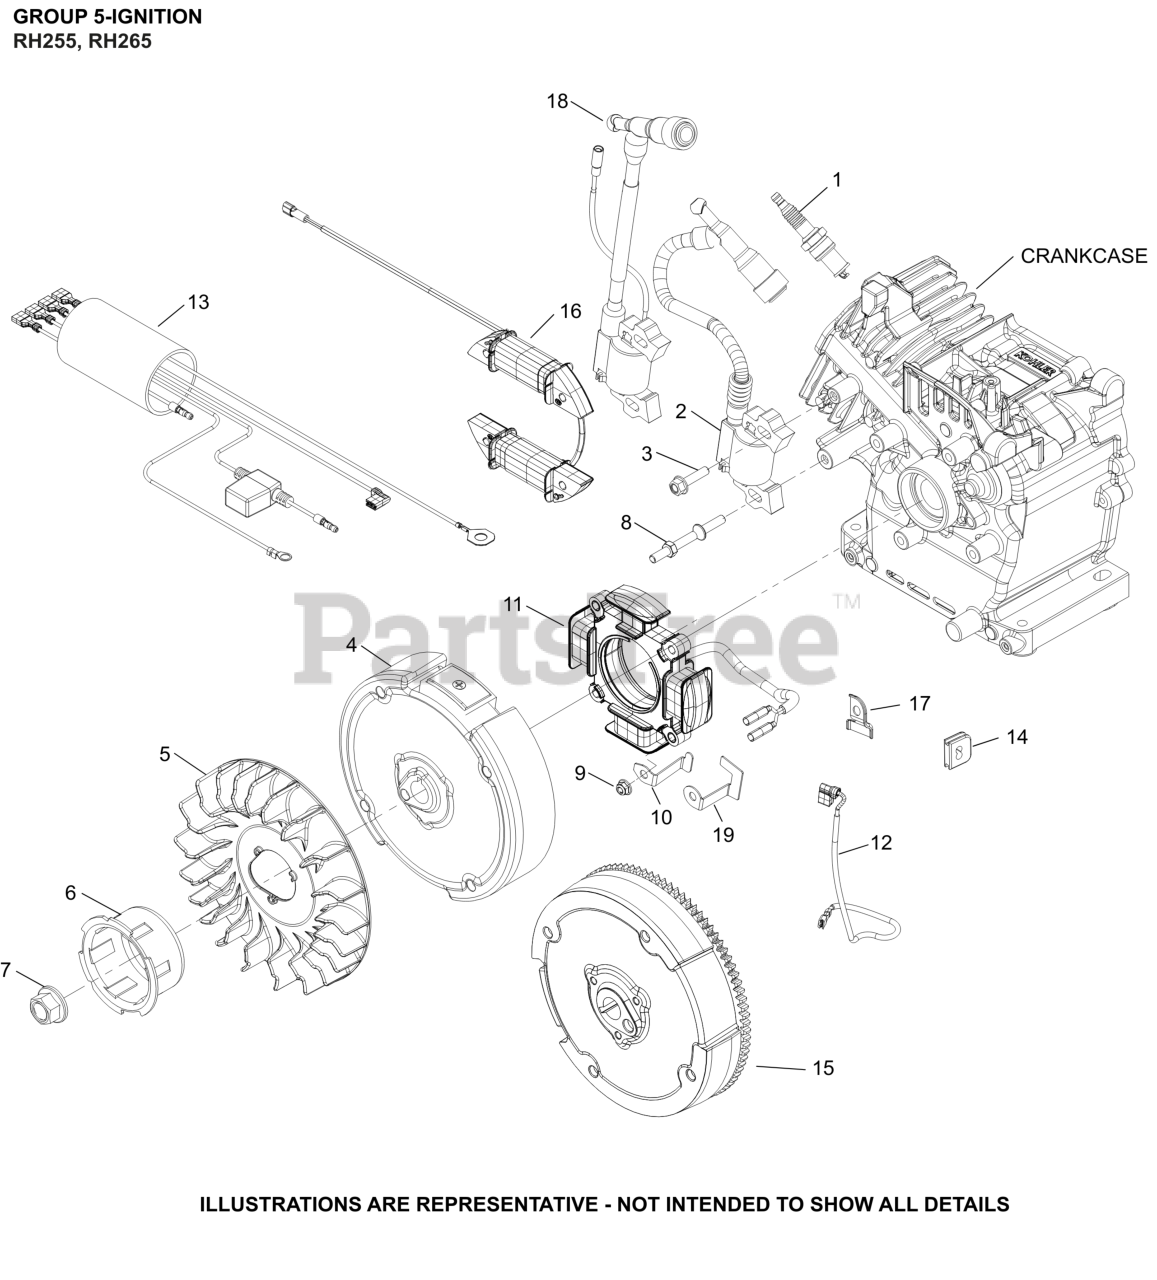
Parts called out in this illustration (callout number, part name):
1	PLUG SPARK 12MM RFI
2	MODULE, IGNITION
3	SCREW, M6 X 25-(#25086436S)
4	FLYWHEEL, ASSEMBLY
5	FAN, FLYWHEEL
6	CUP, STARTER DRIVE
7	NUT, FLYWHEEL (W/SERRATIONS)
8	STUD, IGNITION MODULE
9	NUT, SELF-LOCKING M5
